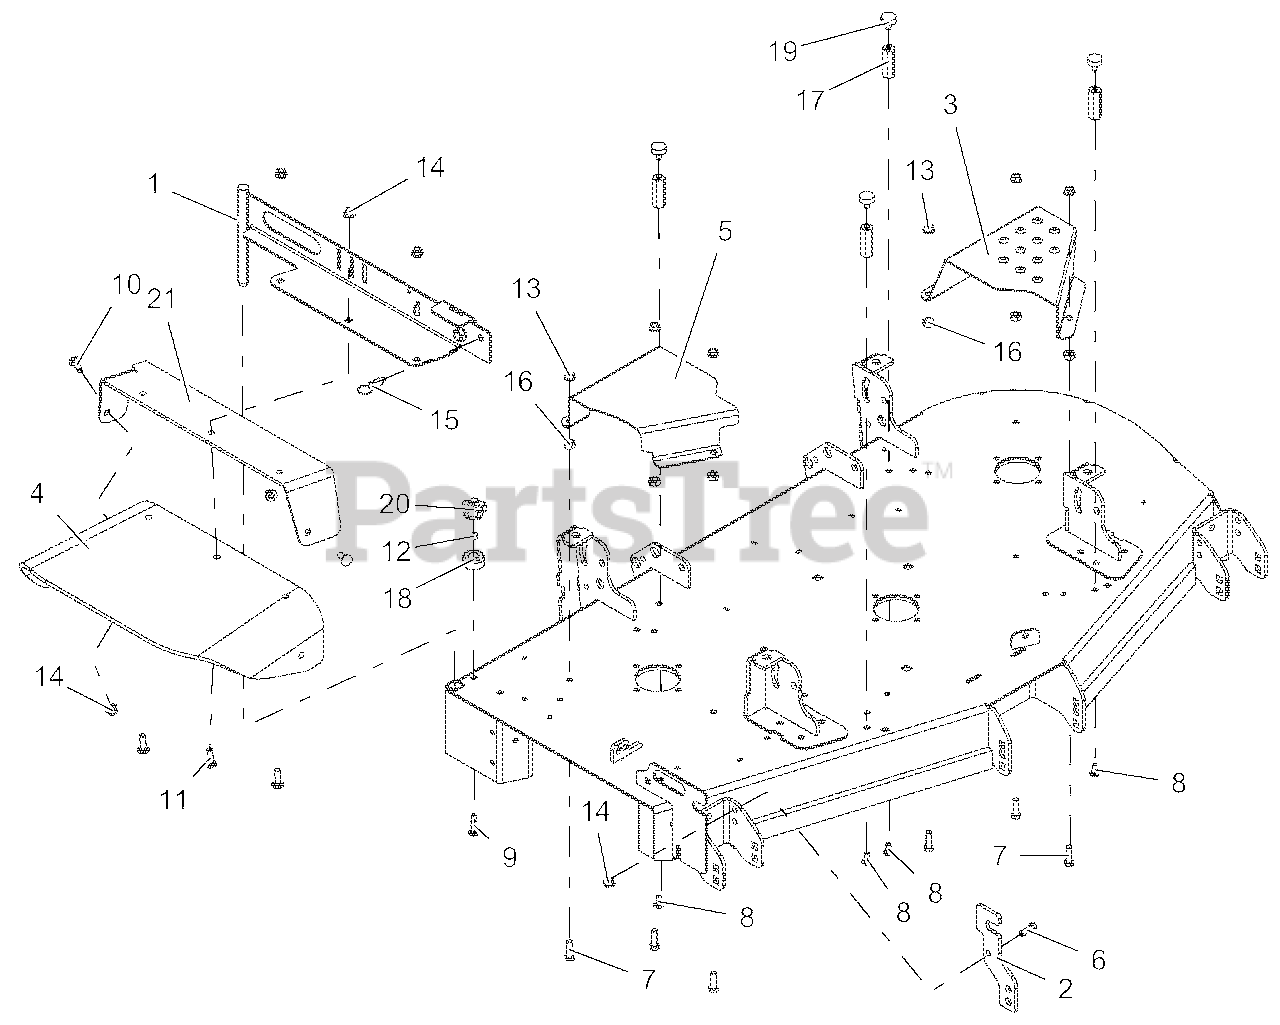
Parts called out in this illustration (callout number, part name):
1	WLDMT, 52"-60" DISCH CHUTE MTG-RED
2	CHUTE STORAGE BRACKET-RED
3	GUARD, 44-52" LH DECK BELT-BLACK
4	CHUTE, RUBBER DISCHARGE
5	GUARD, 48"-52" RH DECK BELT-BLACK
6	BLT-HEX .38-16X1.00 GR5 YWZC
7	BLT-HEX .38-16X1.25 GR5 YWZC
8	BLT, RDHDSQNK .31-18X.75 LOCTITE
9	BLT-RDHDSQNK .31-18X1.50 G5 YWZC
10	BLT-RDHDSQNK .38-16X1.00 G5 YWZC
11	BLT-RDHDSQNK .38-16X1.25 G5 YWZC
12	NUT-LK-CTR .31-18 YWZC
13	@NUT-SPNLK-FLG .375-16 YWZC
14	NUT-LK-NYL-FLG .38-16 YWZC
15	PULL PIN,.50-13THDX.310 PLNGR
16	NUT-HEAVY HEX .38-16 YWZC
17	NUT, .31-18 X 2.25 LG COUPLING
18	BUMPER, RECESSED 1.50 X .63 W/.31 HOLE
19	BUMPER, RUBBER
20	KNOB, CLAMPING
21	DISCHARGE CHUTE SUPPORT W/SAFETY DECAL-RED
